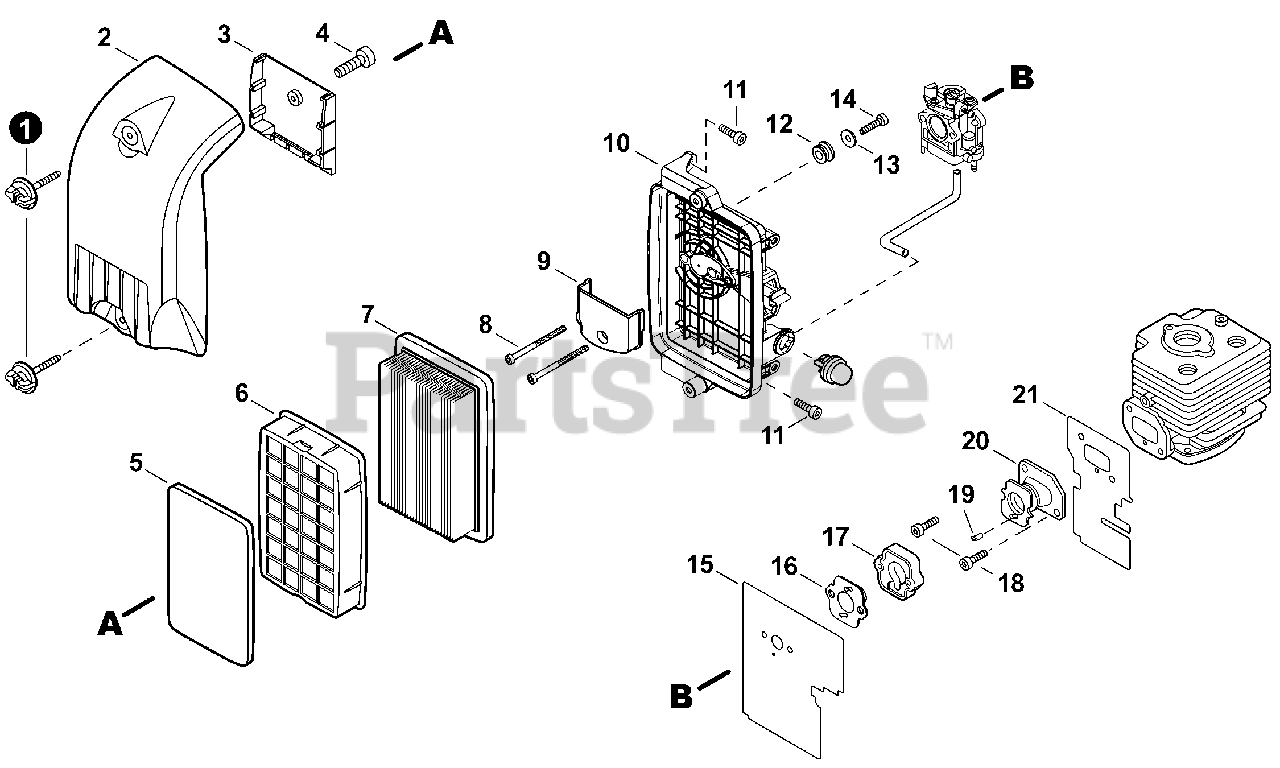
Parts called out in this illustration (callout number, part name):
1	THUMBSCREW
2	COVER, AIR FILTER
3	SUPPORT, PRE-FILTER
4	BOLT, TORX 4×12
5	PRE-FILTER, FOAM
6	RETAINER, PRE-FILTER
7	FILTER, AIR
8	BOLT, TORX 5×55
9	PLATE, PREVENT
10	CASE, AIR FILTER
11	BOLT, TORX 5×20
12	GUIDE, CABLE
13	WASHER 5.5×16×0.8
14	BOLT, TORX 5×16
15	HEAT SHIELD, INTAKE
16	GASKET, INTAKE
17	ADAPTOR, INTAKE
18	SCREW 5×12
19	COLLAR 3
20	BELLOWS, INTAKE
21	HEAT SHIELD, INTAKE
